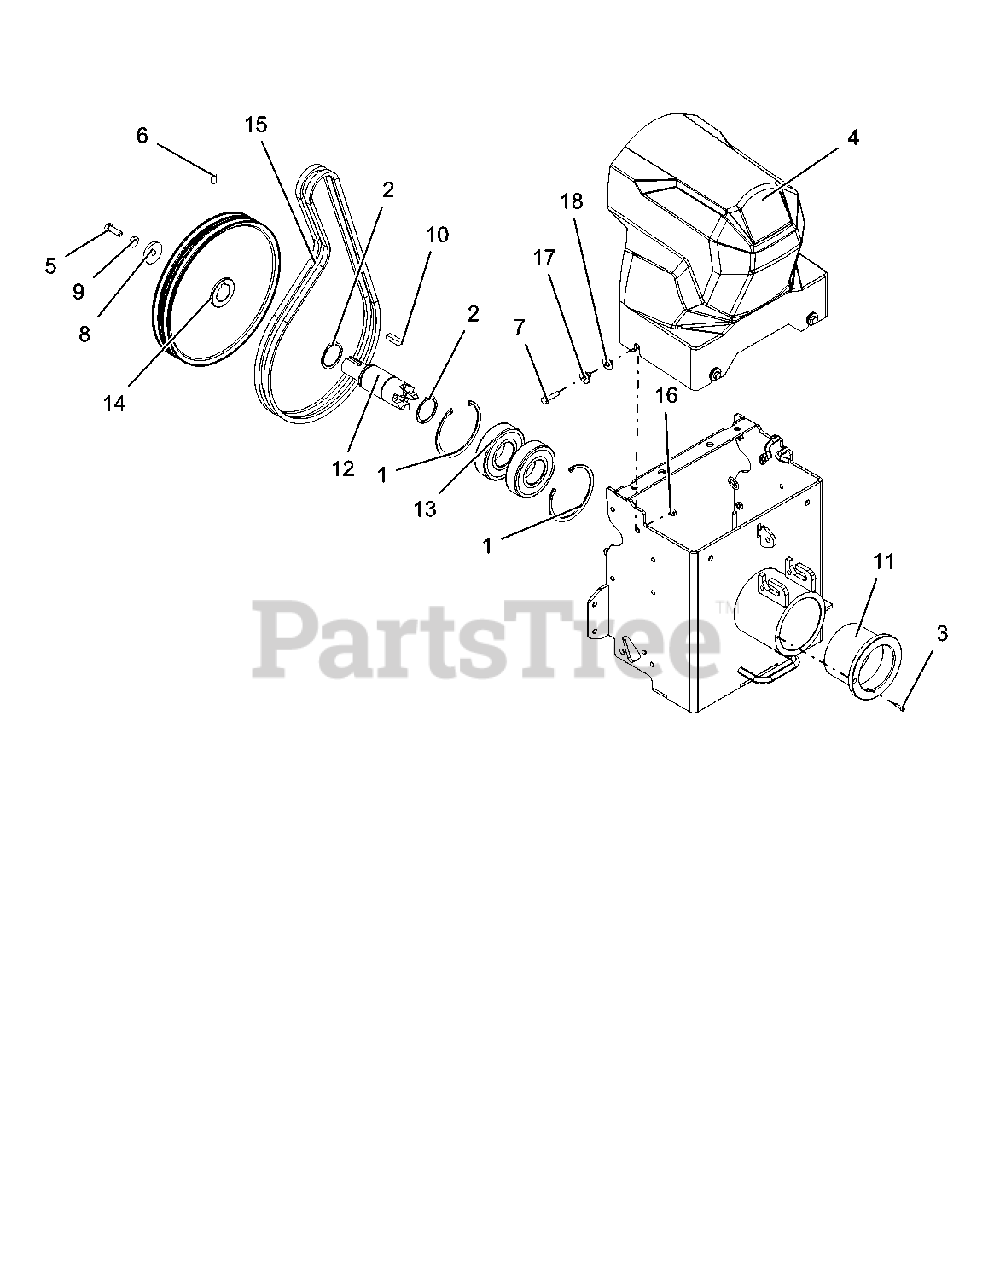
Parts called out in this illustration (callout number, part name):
1	RING, RETAININT - INT 4.250X.109
2	RING, RETAINING-EXTERNAL 50MM X 2MM
3	SCR, SKH M5-.8 X 16 GR12.9 ROHS
4	COVER, FRONT BELT
5	BLT, HEX M10-1.5X30 GR8.8 ZC120
6	SCR-SET .38-24X.750 SK CUP
7	BLT, HEX M8-1.25X35 GR8.8 ZC120
8	WSHR-FL-STL .406X1.750X.250 ROHS
9	WSHR, 3/8" SPRING DISC
10	KEY, SQ 3/8 X 1.250
11	BUSHING, OUTPUT
12	SHAFT, PTO
13	BRG, BALL 6310-2RS
14	PULLEY, DBL PTO INPUT
15	V-Belt, HA-DOUBLE CLUTCHING COVER (Set)
16	NUT, LK-CTR-JAM M8-1.25 GR8.8 ZC120
17	BSHG, BELT COVER
18	WSHR, RUBBER, .093X.425X1.250 DUR 56A
